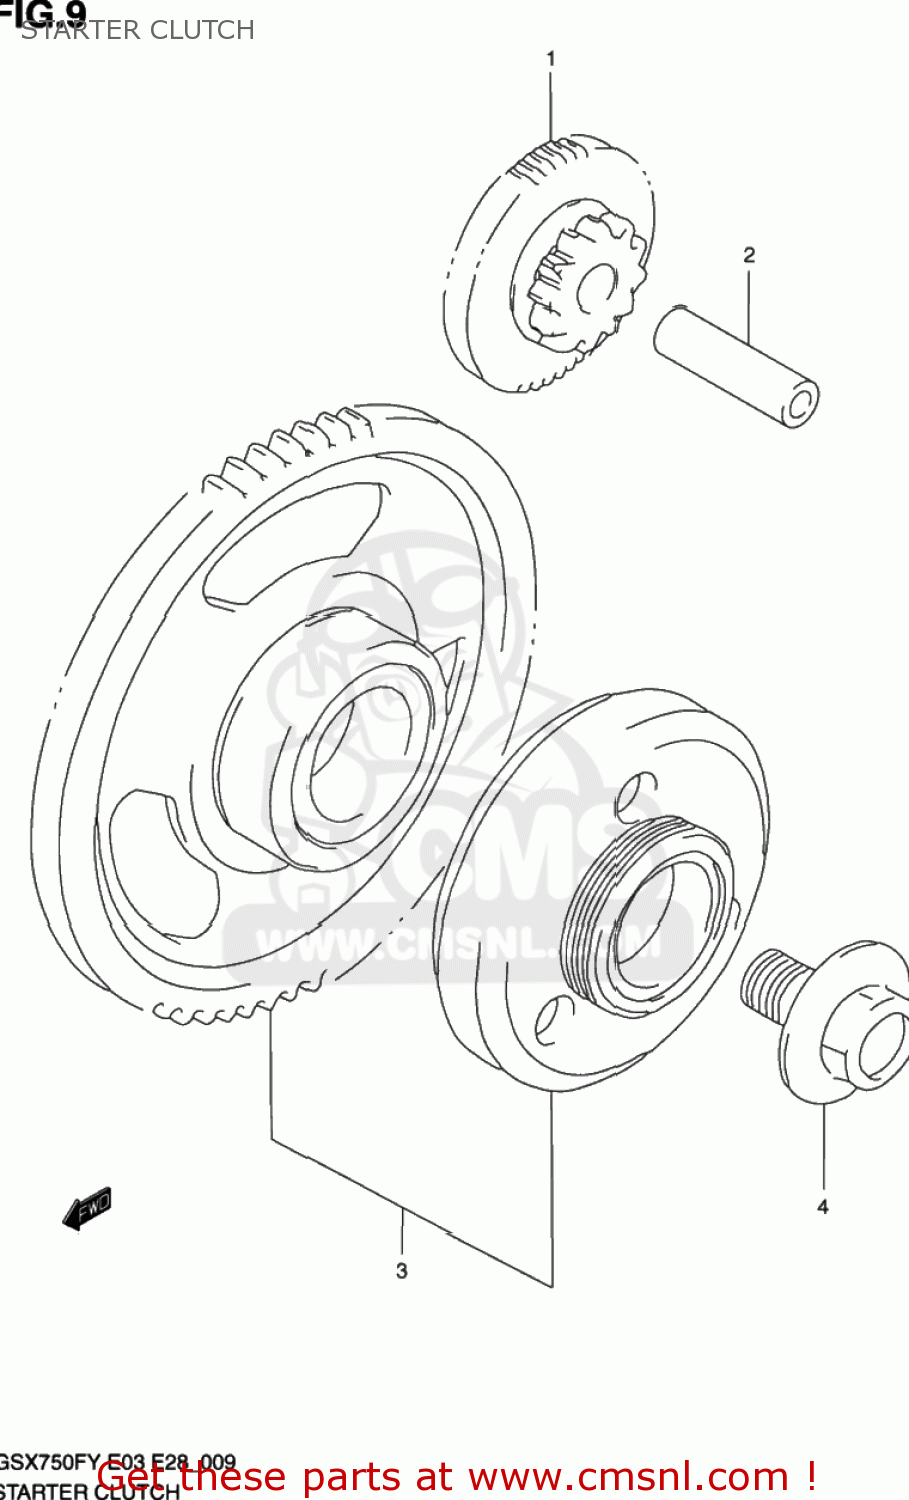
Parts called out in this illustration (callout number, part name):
1	GEAR,STARTER IDLE(NT:12,53)
2	PIN(7X11X42)
3	CLUTCH SET,STARTER
4	BOLT(14X21)
